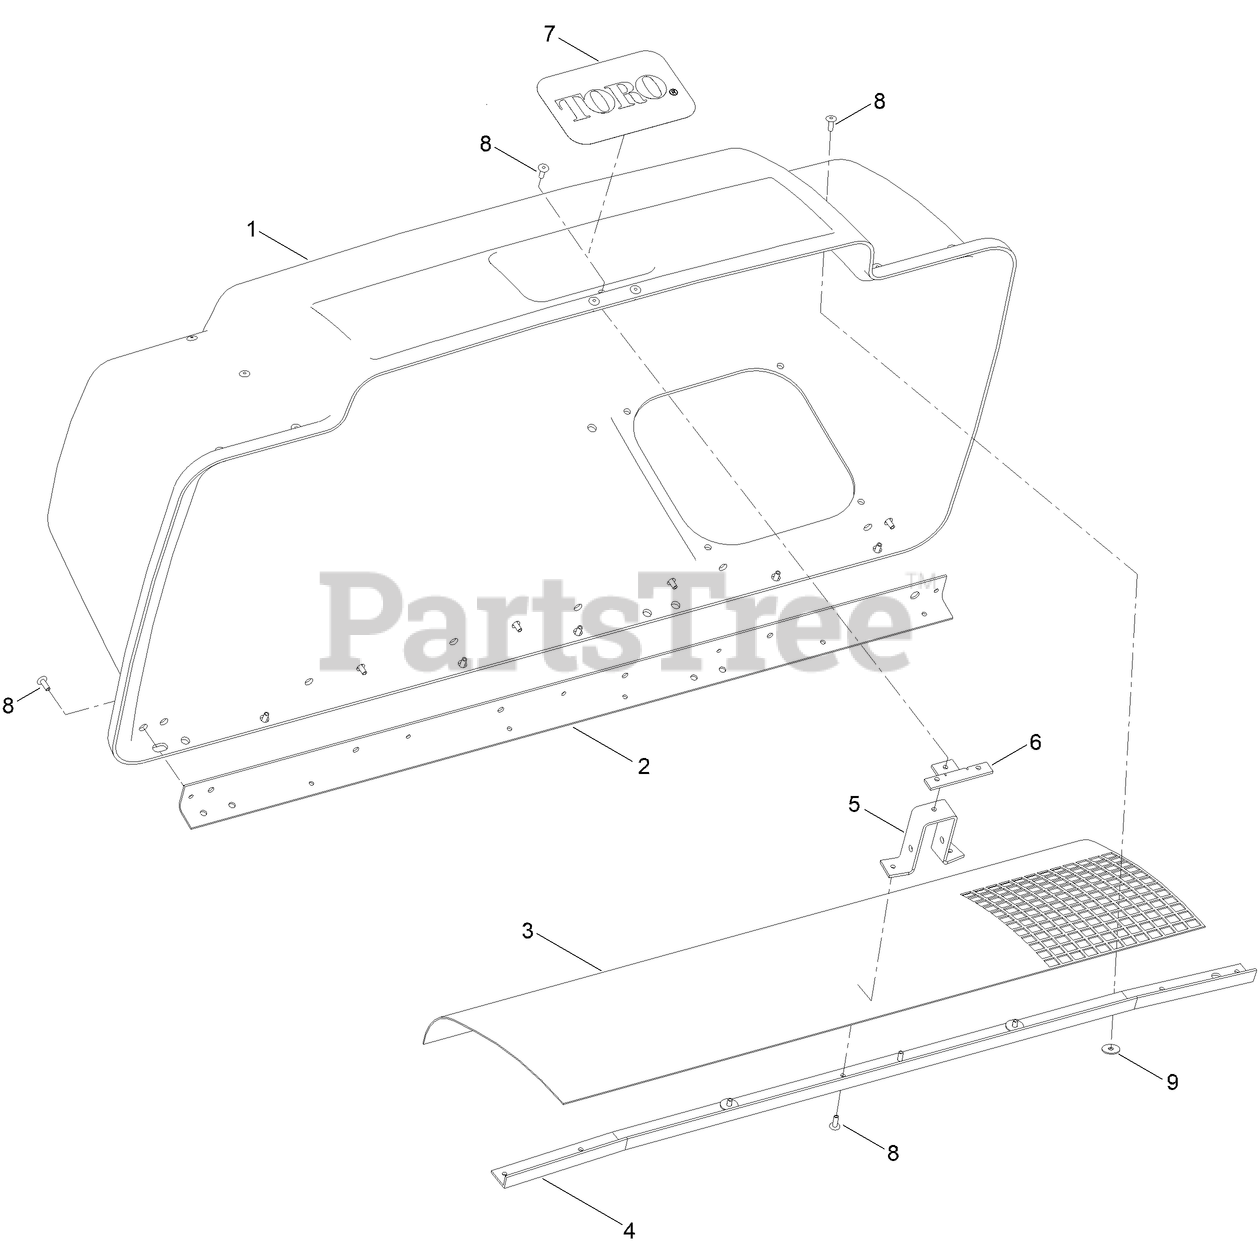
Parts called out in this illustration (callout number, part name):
1	TOP-BAGGER
2	STIFFENER-BAGGER, TOP
3	SCREEN-BAGGER
4	SUPPORT-SCREEN
5	ANCHOR-LATCH
6	REINFORCEMENT-LATCH
7	DECAL
8	RIVET-BLIND
9	WASHER-FLAT
